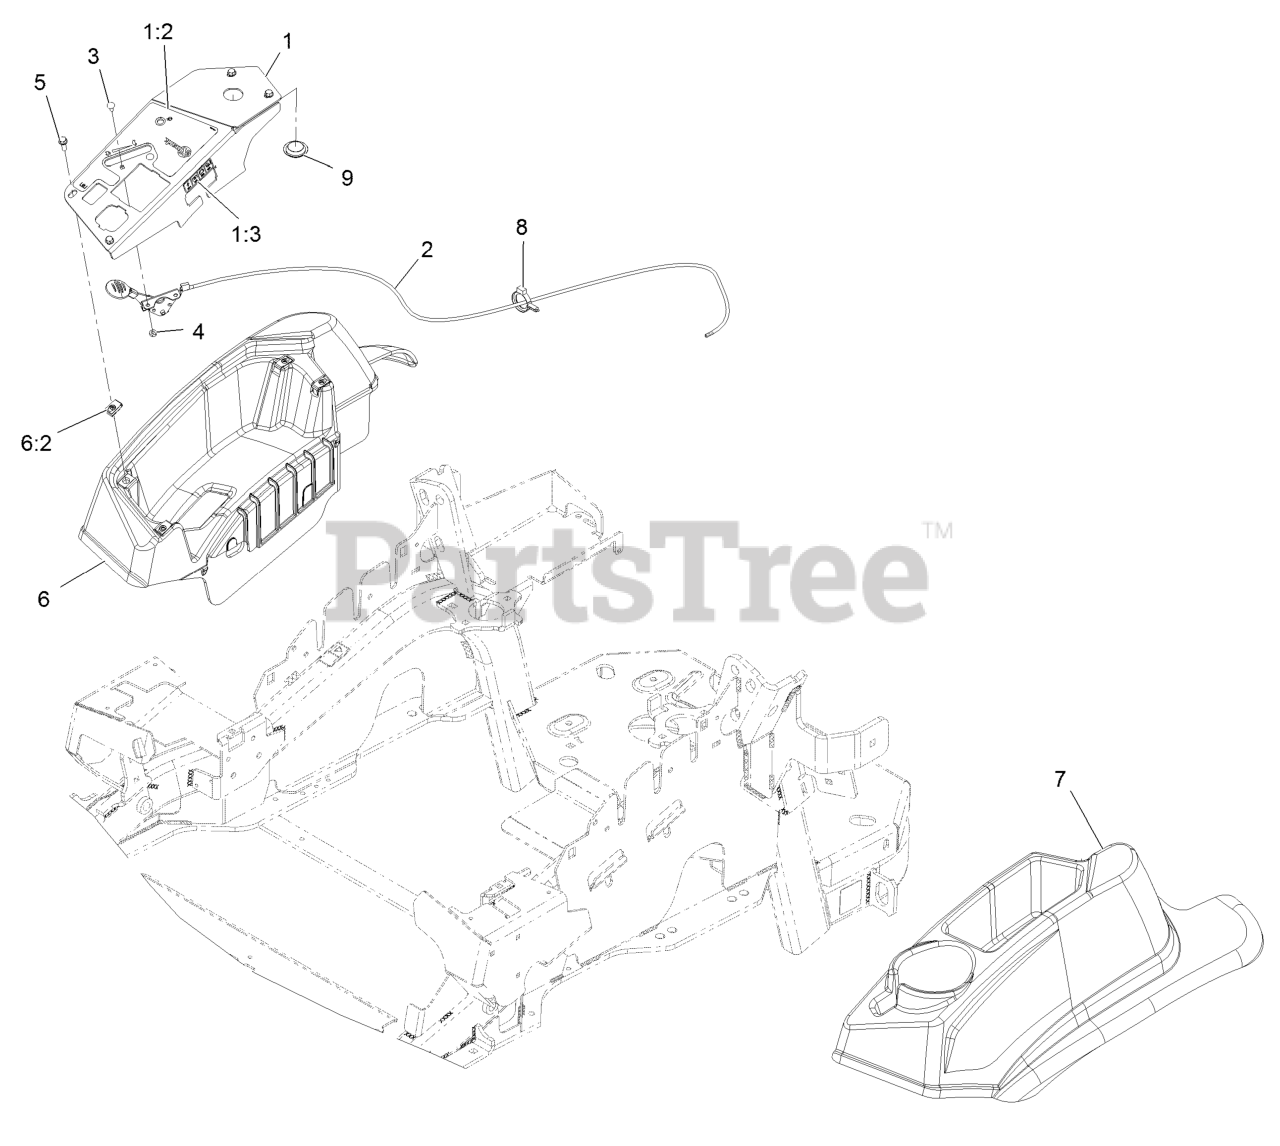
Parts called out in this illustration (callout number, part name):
1	ASM,CONTROL PANEL W/DECAL
1:2	DECAL-CONTROL PANEL EFI
1:3	DECAL-FUSES
2	ASM,THROTTLE CABLE
3	BOLT-CARR
4	NUT-LOCK, NI
5	SCREW-HWH
6	CONSOLE,RH AS ASM
6:2	Nut-Retainer-Panel 1/4-20
7	CONSOLE, LH AS
8	CLAMP-HOSE
9	PLUG-PLASTIC
